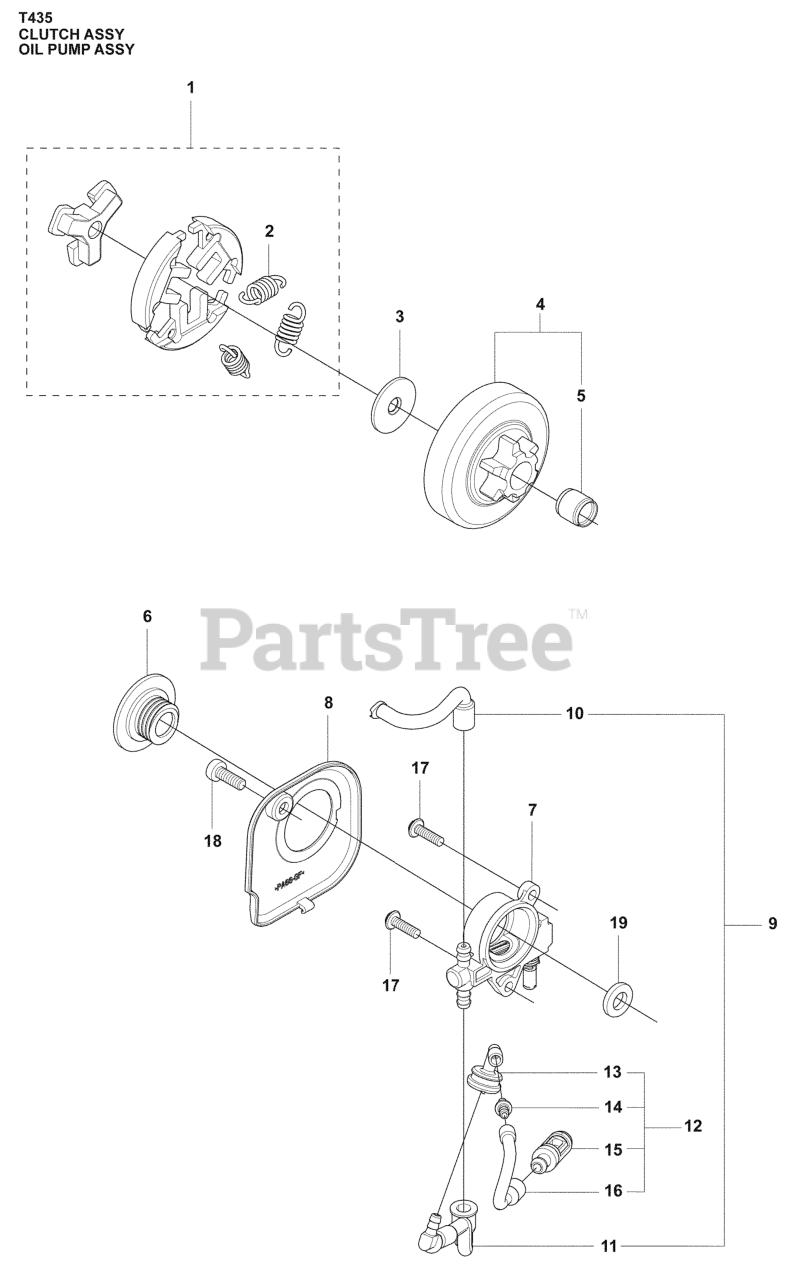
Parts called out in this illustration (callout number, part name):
1	CLUTCH-ASSY
3	PLATE
4	DRUM
5	BEARING
6	OIL PUMP (WORM 199-18)
7	OIL PUMP ASSY
8	COVER PUMP
9	PIPE IN COMP
11	PIPE, OIL IN
12	FILTER COMP
13	PIPE, OIL FILTER
15	FILTER
16	PIPE
19	THRUST WASHER
